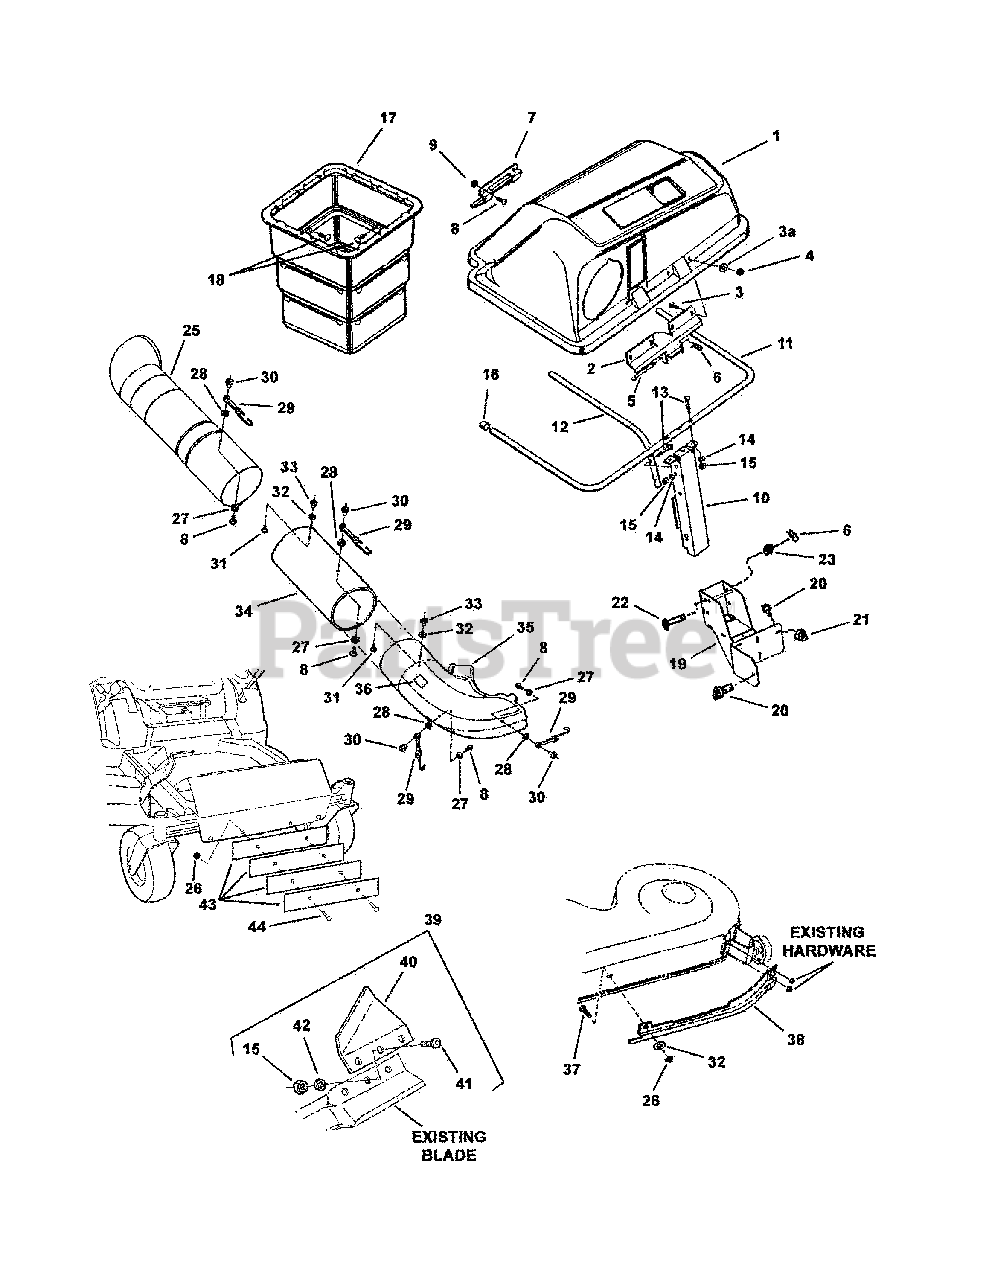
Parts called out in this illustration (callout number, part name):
1	TWIN COVER ASSEMBLY, 38"
2	HINGE, Cover
3	BOLT, Carriage, 1/4 - 20 x 3/4
4	LOCKNUT, Hex Center Lock, 1/4 - 20
5	PIN, Cover Hinge
6	PIN, Hair, 3/32 x 1-1/2
7	HANDLE, Cover
8	CROSS RECESS PAN HEAD, 10 - 24 x 5/8
9	LOCKNUT, Hex with Nylon Insert, 10 - 24
10	WELD, Channel Support
13	BOLT, Curved Head, 5/16 - 24 x 1-5/8
14	WASHER, Split Lock
15	NUT, Hex, 5/16 - 24
16	CAP, Tube End
17	NESTABLE CONTAINER ASSEMBLY, Twin Bag
18	PANEL FASTENER
19	WELDMENT, Grass Catcher Support
20	BOLT, Hex Washer Self-Tapping, 5/16 - 18 x 3/4
21	NUT, Locknut Flange, 5/16 - 18
22	PIN, Clevis
23	WASHER, SAE, 1/2
25	TUBE, Upper
26	NUT, Hex Center Lock, 5/16 - 18
27	WASHER, Flat
28	WASHER, Flat
29	STRAP, Mounting Bag Adapter/Tube
30	NUT, Weld - 10/24 Thread
31	SCREW, Cross Recessed Pan Head, 5/16 - 18 x 5/8
32	WASHER, Flat
33	NUT, Tee, 5/16 - 18
34	TUBE, Lower
35	DISCHARGE CHUTE ASSEMBLY, with Decal
36	DECAL, Deflector Chute
37	CAPSCREW, Hex Head , 5/16 x 3/4
38	BAFFLE, 38" Deck
39	AIR LIFT KIT ASSEMBLY
40	AIR LIFT
41	SCREW, Oval Head, 5/16 - 24 x 21/32
42	LOCKWASHER, Internal Tooth Lock, 5/16
43	BALLAST, Twin Bag Catcher
44	BOLT, Carriage, 5/16 - 18 x 1-3/4
